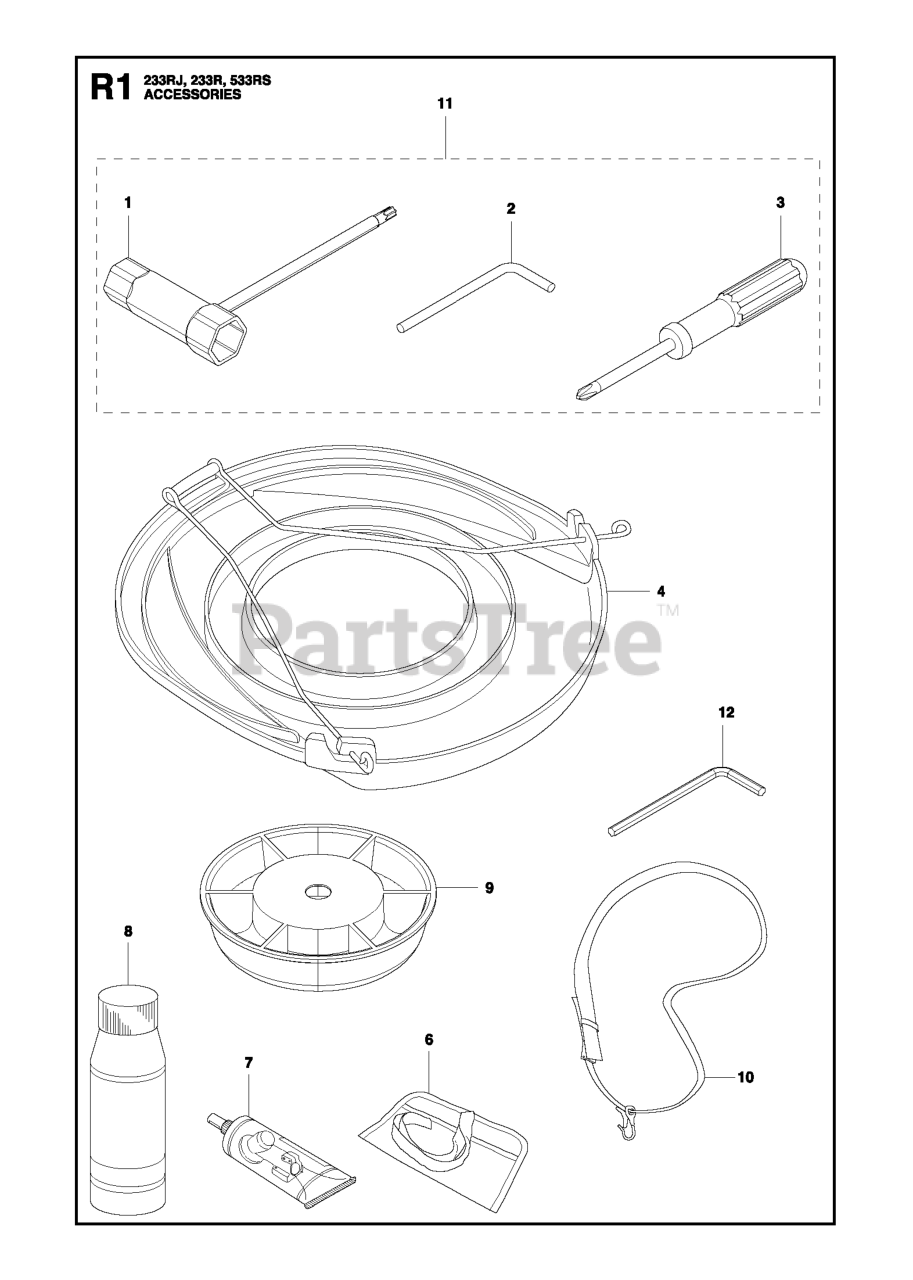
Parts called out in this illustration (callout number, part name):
4	BLADE GUARD TRANSPORT
7	BEVEL GEAR GREASE
8	Air Filter Oil 1l.
9	SUPPORTING CUP
10	Harness-w/o warning
12	WRENCH
